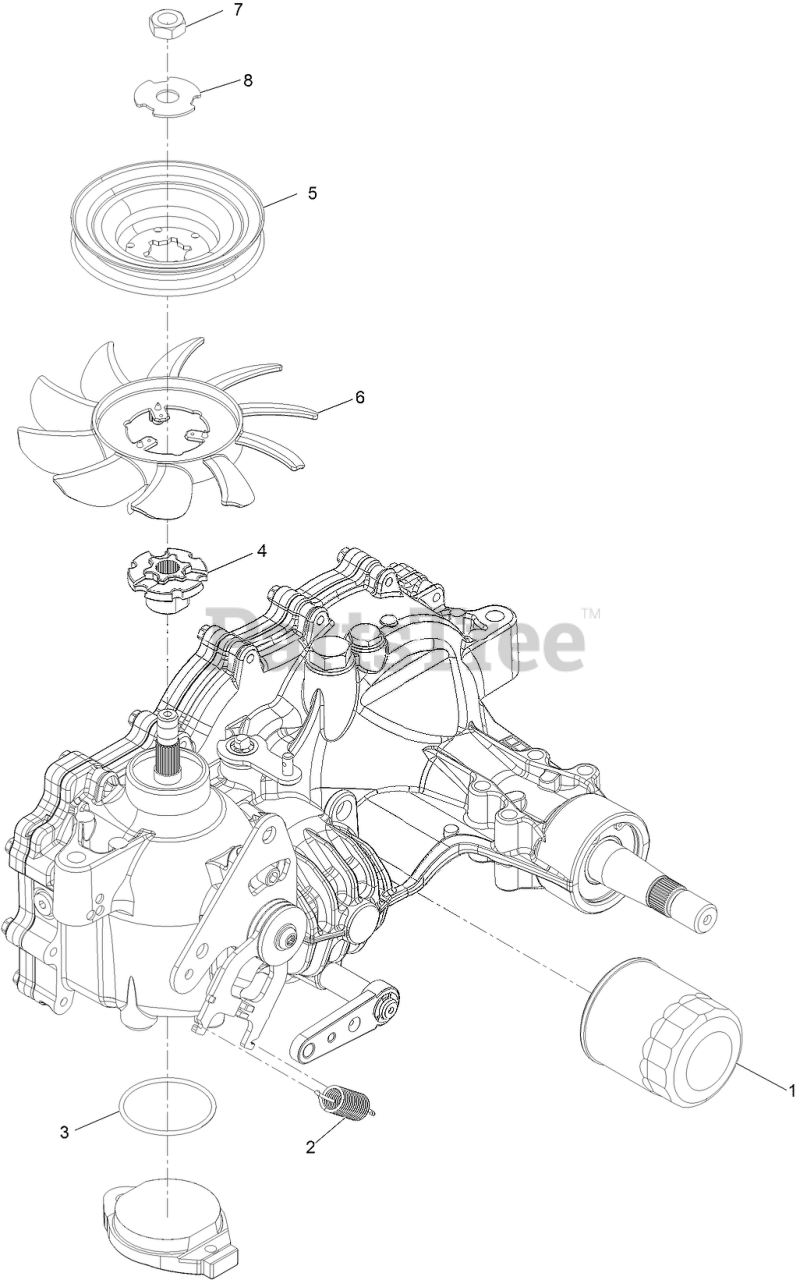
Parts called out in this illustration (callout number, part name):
1	ELEMENT-OIL FILTER, HYD
2	SPRING-EXTENSION
3	O RING-SEAL
4	HUB-PULLEY
8	WASHER-SLOTTED
99	BRAKE SHAFT SEAL KIT
